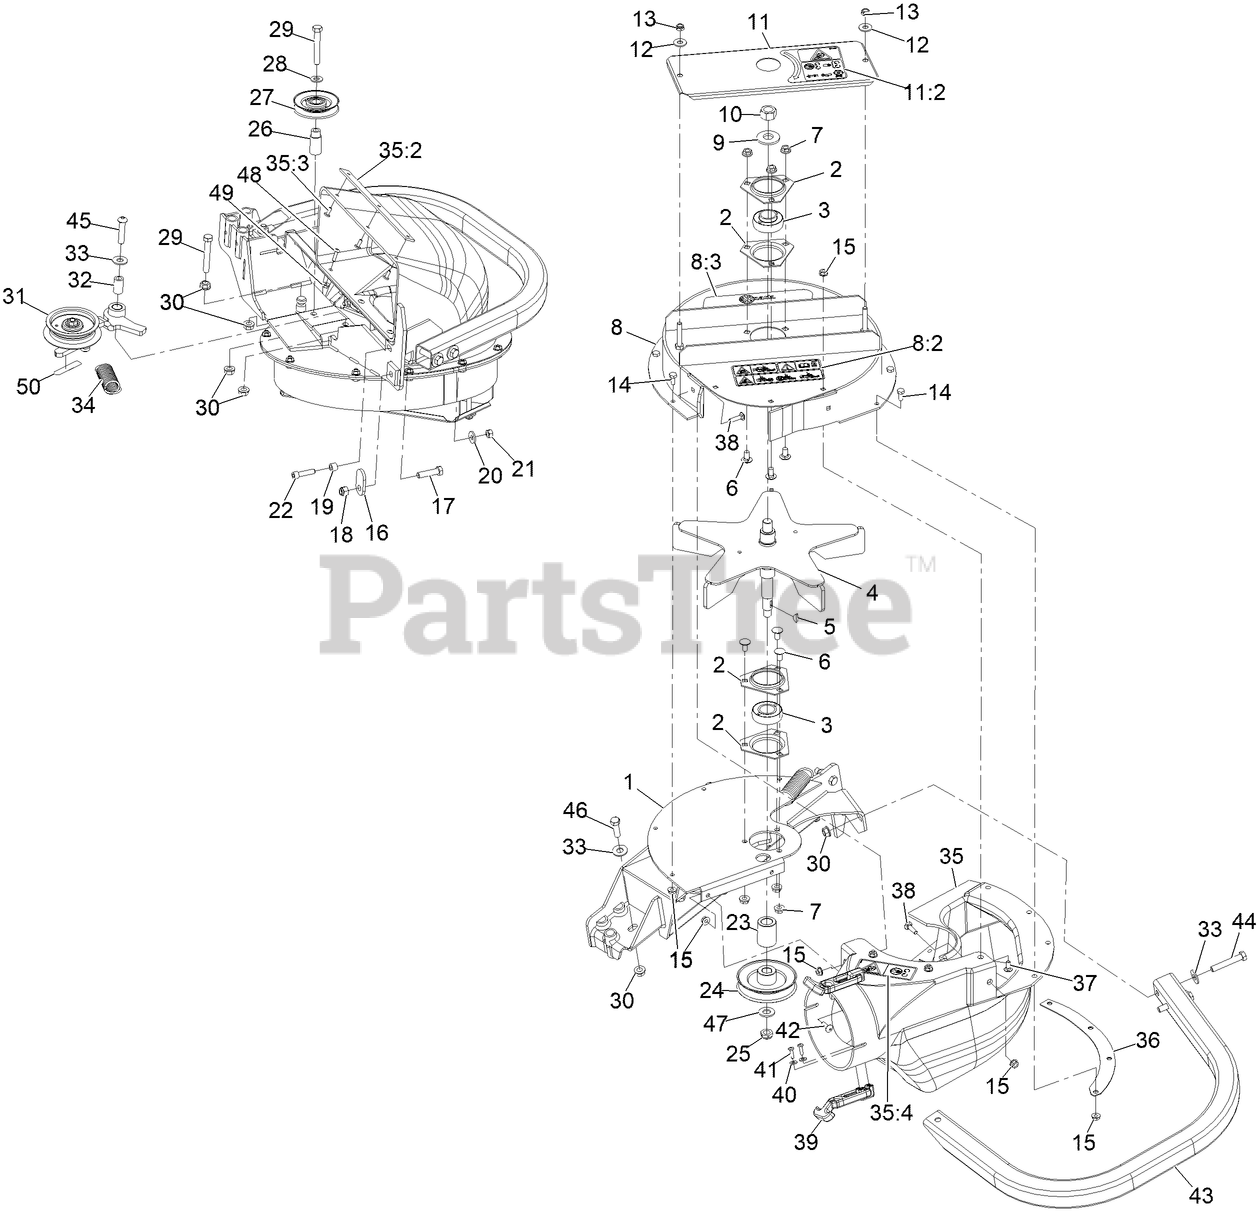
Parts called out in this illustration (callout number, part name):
1	Weld, Blower Frame
2	HOUSING-FLANGE
3	BEARING
4	IMPELLER
5	KEY-WOODRUFF
6	SCREW-CARR
8	UPPER-HOUSING W/DECAL
8:2	DECAL-ULTRAVAC S-SERIES
8:3	DECAL-WARNING
9	WASHER-SPRING
10	NUT-HEX
11	COVER-BEARING W/DECAL
11:2	DECAL-WARNING
12	WASHER-FLAT
13	NUT-LOCK, NI
14	SCREW-HH
16	LATCH-CATCHER, GRASS
17	SCREW-HH
18	NUT-LOCK, NI
19	BUSHING, LOCATOR
20	WASHER-SPRING
21	NUT-HEX
22	SCREW-HSH
24	SHEAVE-BLOWER
25	NUT-LOCK, NI
27	IDLER-INSIDE
28	WASHER-FLAT
29	SCREW-HH
30	NUT-HHF, WHIZ
31	ASM, IDLER
32	BUSHING-PIVOT, IDLER
33	WASHER-FLAT
34	SPRING-IDLER
35	ASM,BLOWER CHUTE LHP
35:2	PLATE-REINFORCEMENT
35:3	RIVET-BLIND
35:4	Decal-Blower-Impeller Hazard
36	PLATE-BACKING, BLOWER
37	SCREW-CARR
38	SCREW-CARR
39	LATCH-RUBBER
40	WASHER-FLAT
41	SCREW-PPH
44	SCREW-HH
45	SCREW-HSBH
46	SCREW-HH
47	WASHER-FLAT
48	SCREW-HEAD, TRUSS
50	DECAL-WARNING
